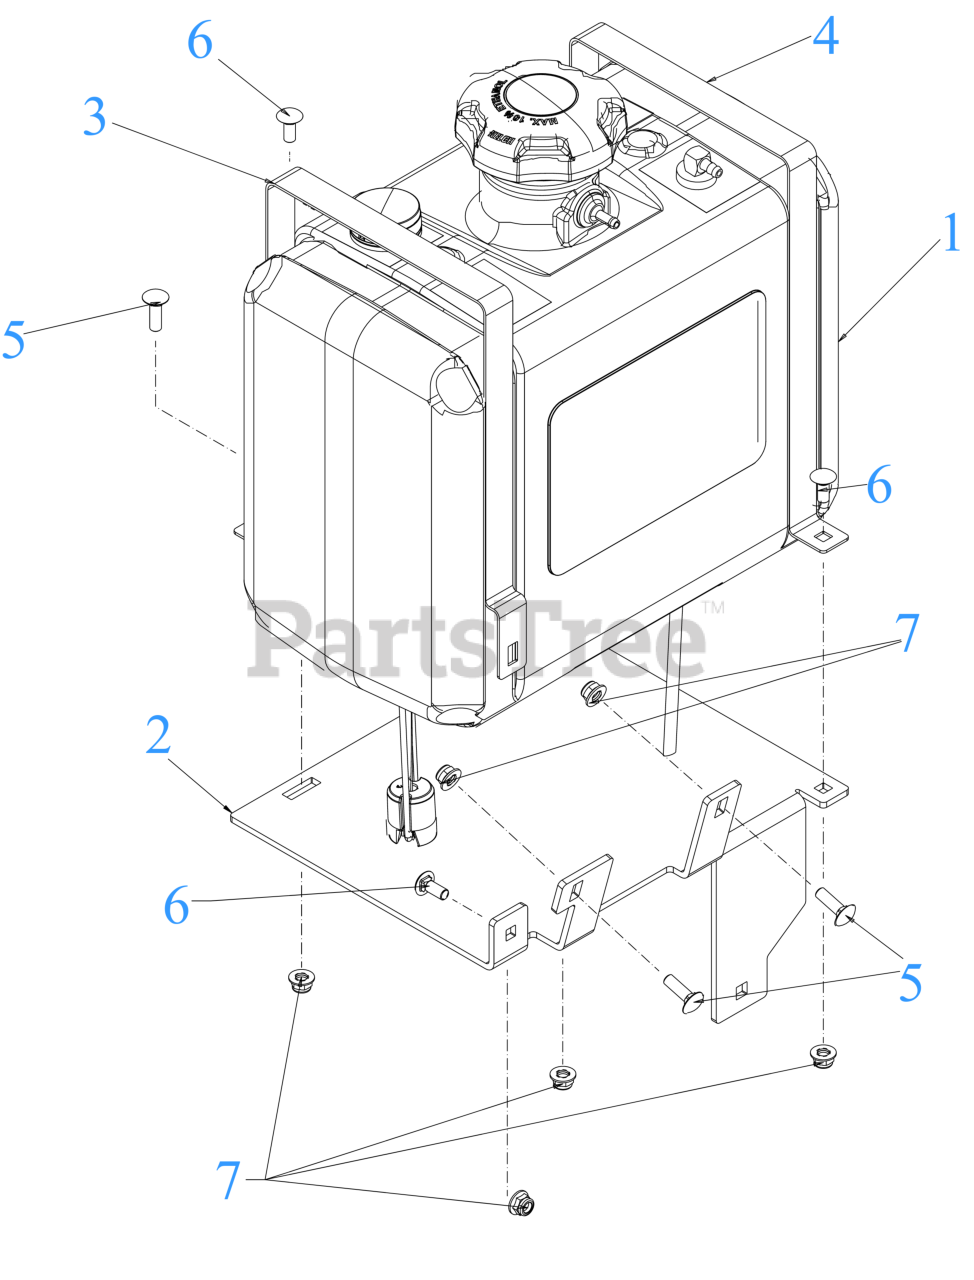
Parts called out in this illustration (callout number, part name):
1	FUEL TANK (6 GAL)
1	FUEL CAP 3.5" W/TETHER
2	TANK MOUNT BRACKET
3	FUEL TANK STRAP
4	TANK MOUNT STRAP
5	CARRIAGE BOLT 5/16-18 x 1.00
6	CARRIAGE BOLT 5/16-18 x .75
7	FLANGE LOCK NUT 5/16-18
